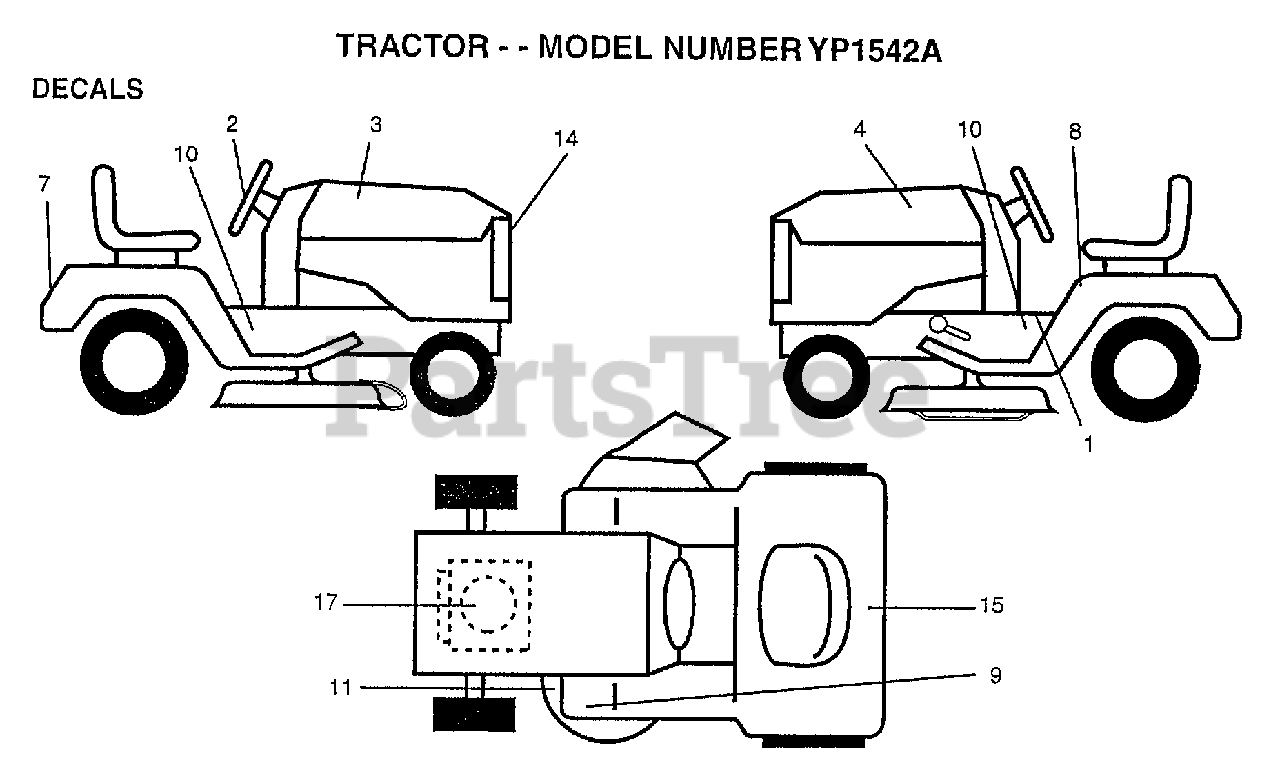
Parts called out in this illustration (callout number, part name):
1	"DECAL DASH,OPER."
2	DECAL INS STRG WH
3	"DECAL HOOD,RH"
4	"DECAL HOOD,LH"
7	DECAL FENDER
8	"DECAL DANGER,FEND"
10	DECAL CHASSIS
11	DECAL
15	DECAL.BATRY.3-3908
